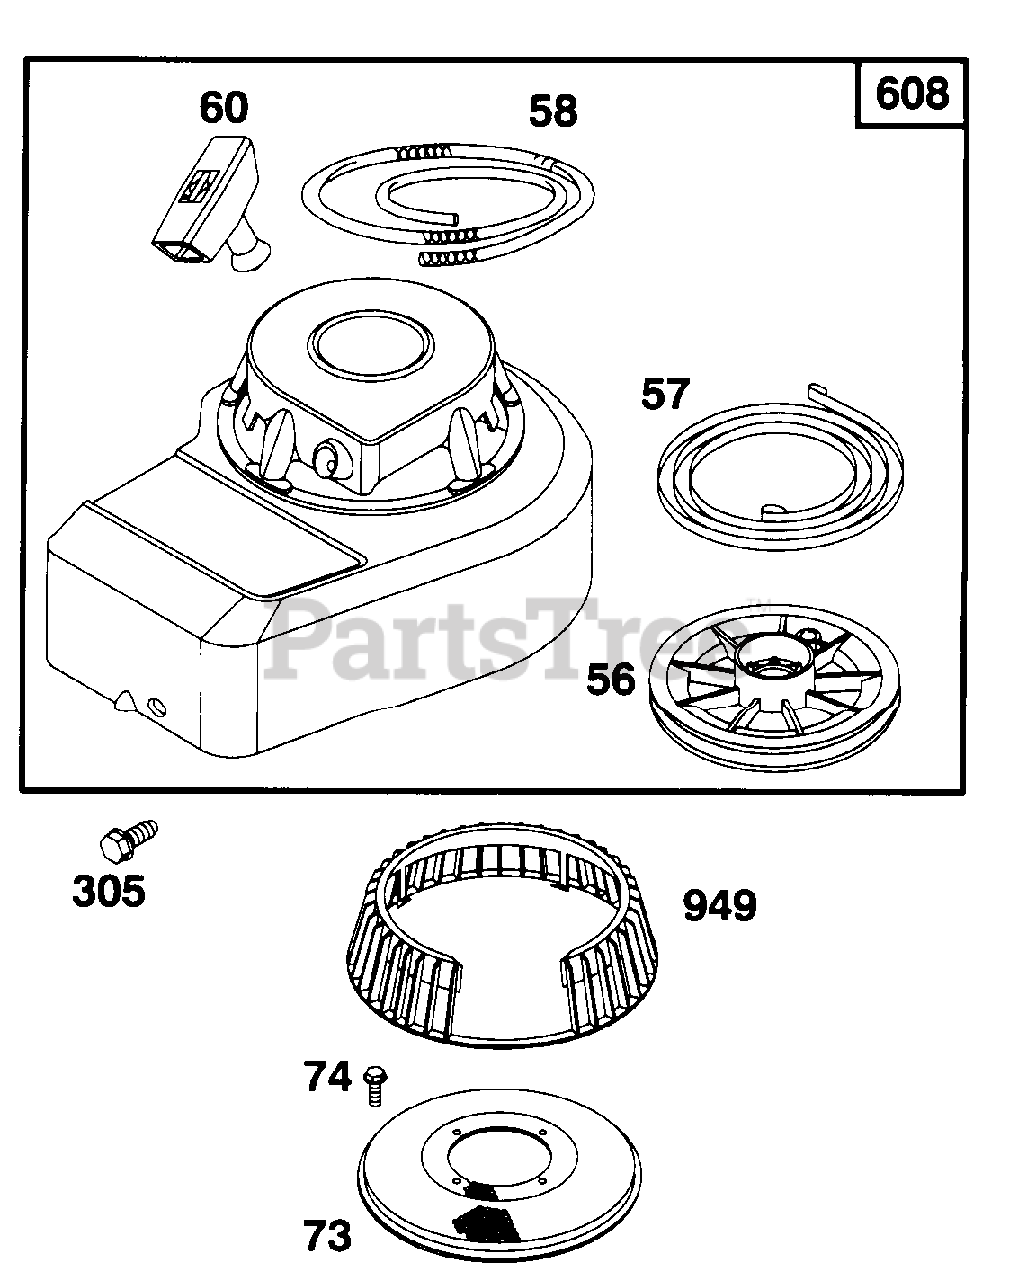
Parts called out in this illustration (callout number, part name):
56	Pulley-Starter
57	Spring-Rewind Starter
58	Rope-Starter
60	Grip-Starter Rope
73	Screen-Rotating
74	Screw-Sem
305	Screw-Hex. Head
608	Starter-Rewind
949	Guard-Finger
